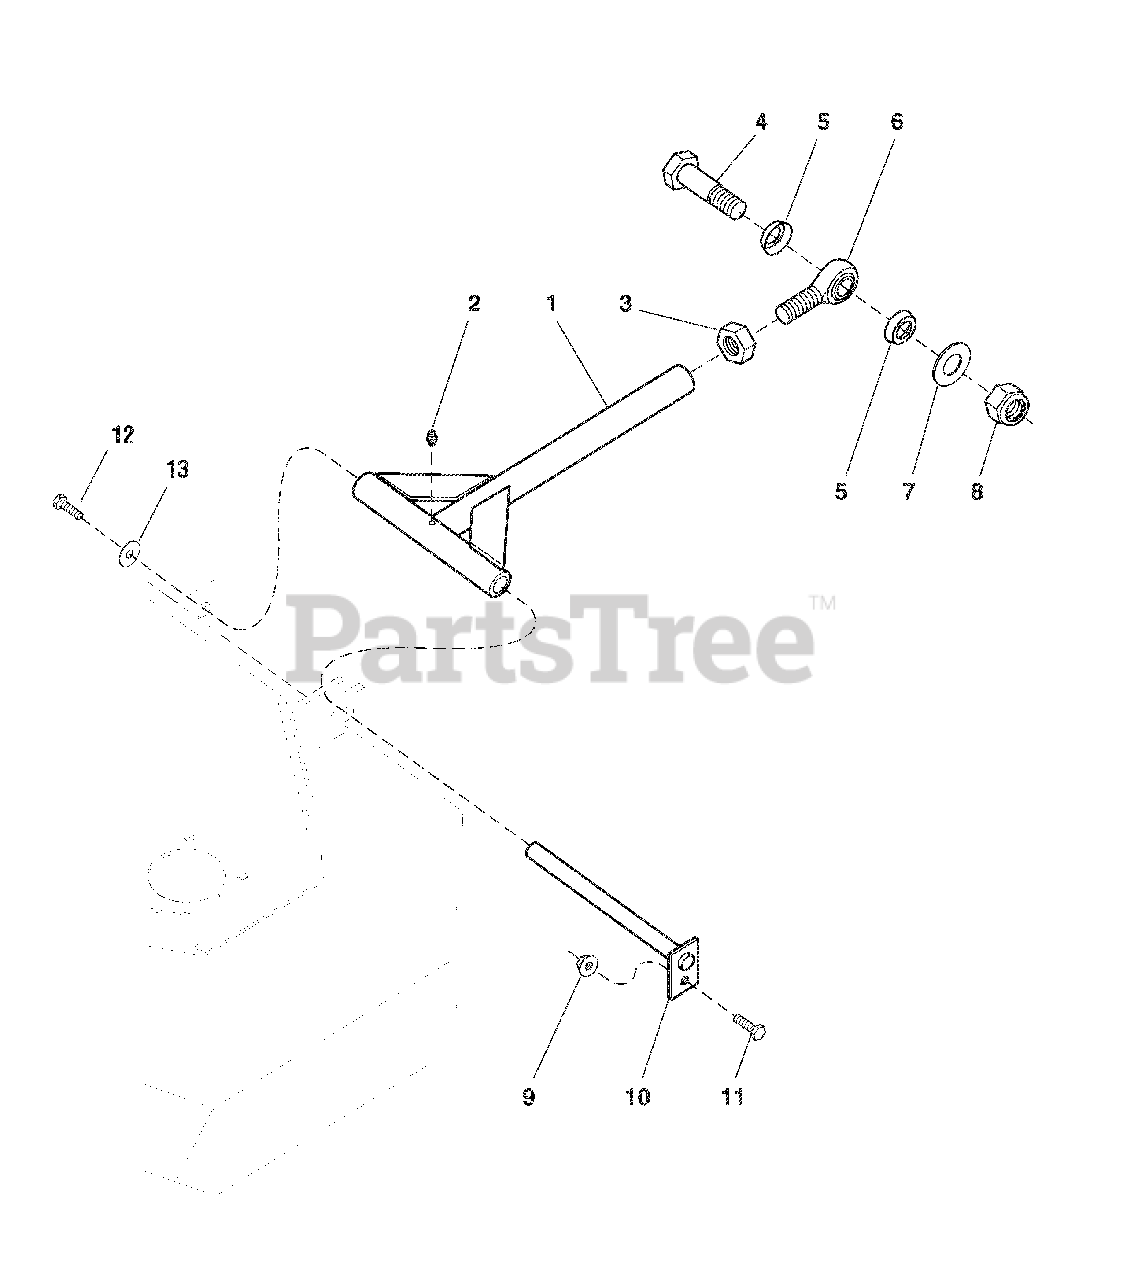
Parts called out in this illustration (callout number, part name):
1	61" DECK PUSHER BAR
2	GREASE FITTING
3	NUT, Hex, Jam, 3/4-16
4	CAPSCREW, Hex Hd, 3/4-16 x 3
5	ROD END SEAL
6	BALL JOINT, 3/4-16
7	WASHER, 3/4
8	NUT, Hex, Nylon Lock, 3/4-16
9	NUT, Hex, Serrated Flange, 5/16-18
10	PUSHER BAR MOUNT PIN
11	CAPSCREW, Hex Hd, 5/16-18 x 1
12	BOLT, 3/8-16 X 1 GD5 YZ
13	WASHER, .390 X 1.50 X .109 YZ
